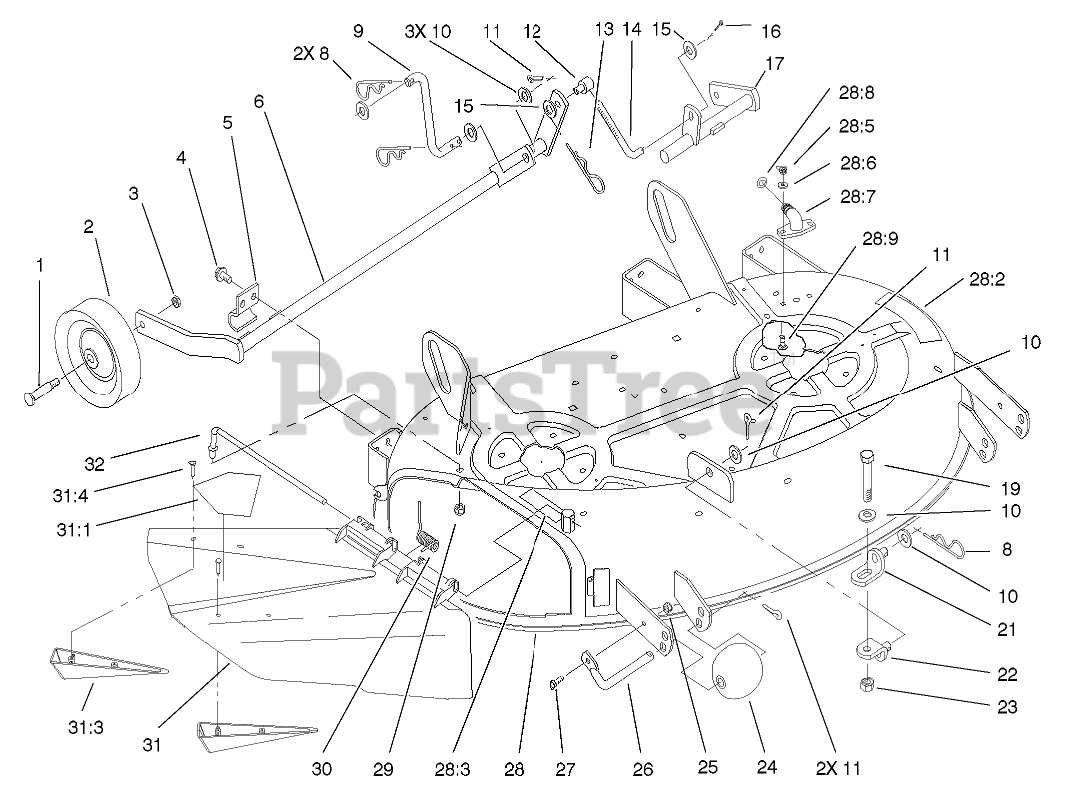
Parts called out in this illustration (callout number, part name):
1	BOLT-SHOULDER
2	WHEEL
3	NUT-HEX
4	SCREW-HWH, TAPTITE
6	SHAFT-RH
8	PIN-COTTER, HAIR
9	LINK-REAR
10	WASHER-FLAT
11	PIN-COTTER
12	TRUNNION
13	PIN-HAIR
14	ROD-LIFT
15	WASHER-FLAT
16	PIN-COTTER
17	SHAFT-LH
19	SCREW-HH
21	BRACKET-LIFT, LOWER
22	BRACKET-LIFT, UPPER
23	NUT-JAM
24	ROLLER
25	NUT-LOCK, NI
26	Shaft-Roller
27	SCREW-HH
28	DECK ASM
28:2	DECAL-DANGER
28:3	DECAL - DANGER
28:5	NUT-LOCK, NI
28:6	WASHER-FLAT
28:7	FITTING-WASHOUT
28:8	O-RING
28:9	BOLT-CARR
29	NUT-LOCK, NI
30	SPRING
31	DEFLECTOR ASM
31:1	DECAL-DANGER
31:3	KICKER
31:4	SCREW-PPH
32	ROD-PIVOT
